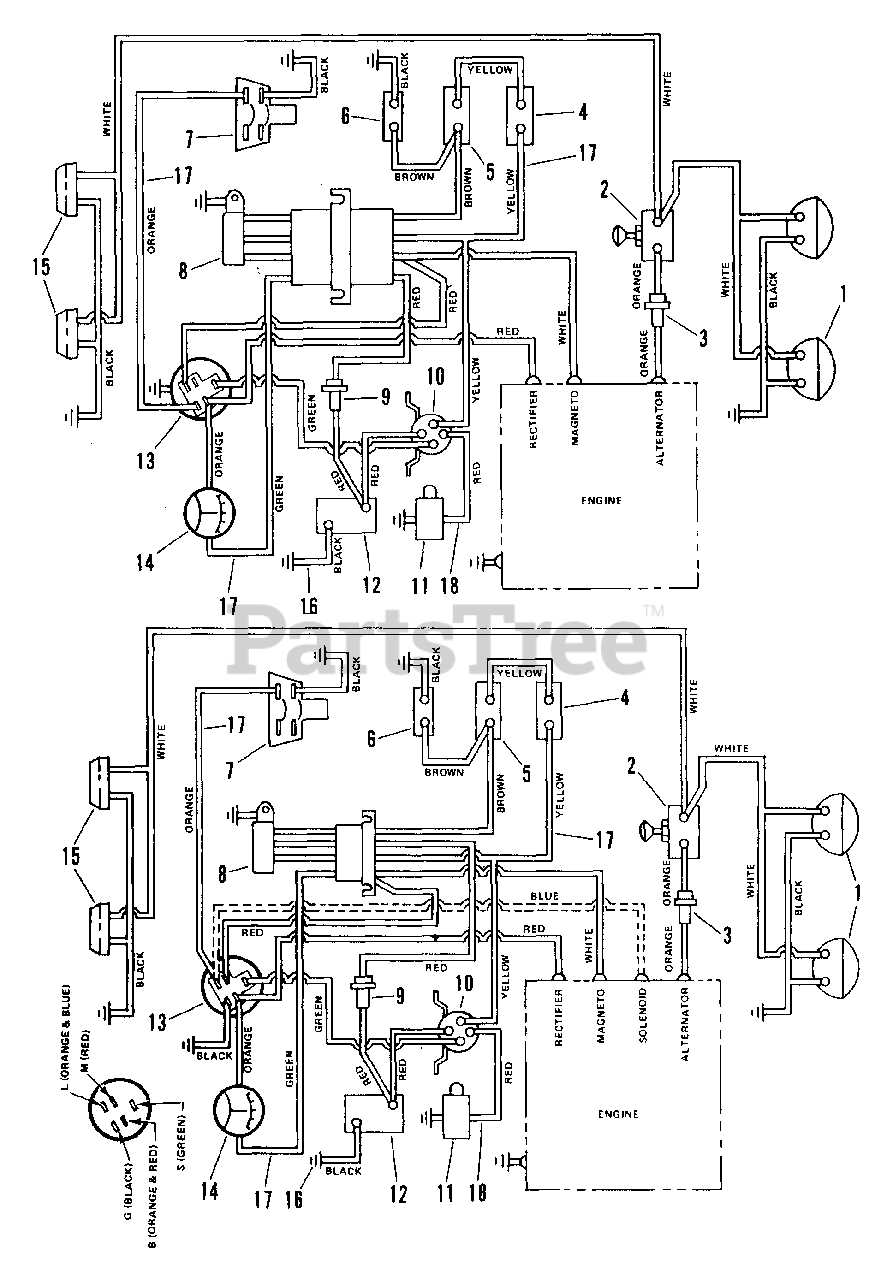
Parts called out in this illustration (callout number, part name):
1	HEAD LIGHT SYSTEM
1	GRILL & LENS ASSEMBLY
1	HEADLIGHT BULB, 1156
2	LIGHT SWITCH ASSEMBLY
2	LIGHT SWITCH
2	PUSH/PULL CONTROL KNOB
4	SWITCH INTERLOCK
5	SWITCH-NEUTRAL START N.O.
6	SWITCH SEAT
7	ACCESSORY CONNECTOR
8	MODULE
10	SOLENOID
11	STARTER MOTOR
12	BATTERY
13	SWITCH ASSEMBLY
14	AMMETER
15	RIGHT TAIL LIGHT
15	LEFT TAIL LIGHT
15	#168 WEDGE BASE BULB
16	GROUND CABLE .25X6.50X.31
17	WIRING HARNESS
18	STARTER CABLE 6.75"
